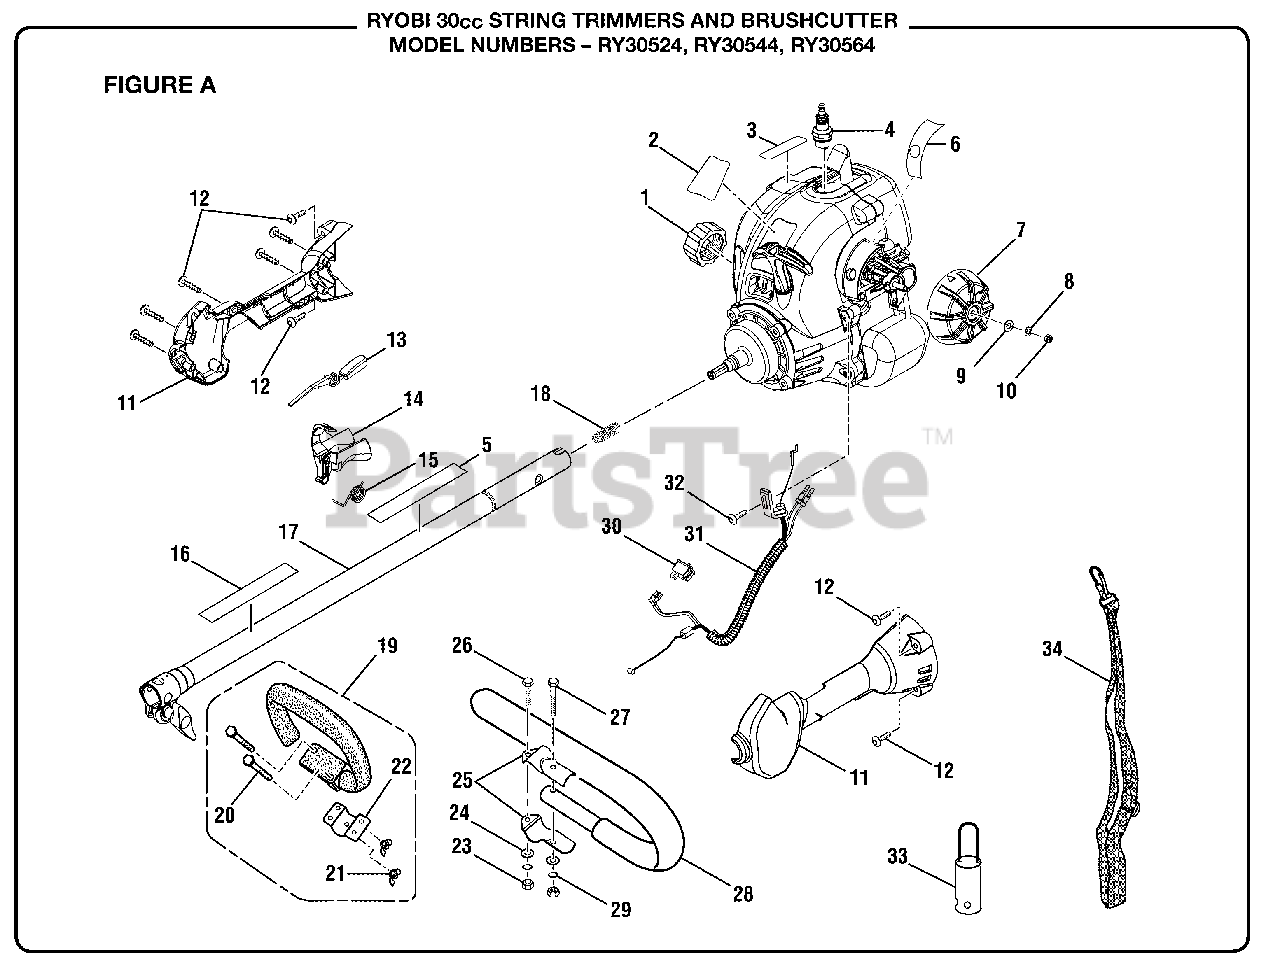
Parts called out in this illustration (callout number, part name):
1	Fuel Cap Assembly
2	Model Label (CS30)
3	Logo Label
4	Spark Plug
5	Starting Label
6	Choke Label
7	Choke Dial Cover
8	Wavy Washer
9	Flat Washer
10	Hex Nut (M4)
11	Control Handle Assembly
12	Screw (10-14 x 1 in.)
13	Trigger Lock
14	Trigger
15	Torsion Spring
16	Warning Decal (CS30 and SS30)
17	Upper Boom Assembly (CS30 and SS30)
18	Compression Spring
19	Front Handle Assembly (CS30 and SS30)
20	Bolt (M5 x 30 mm Hex Hd.) (CS30 and SS30)
21	Wing Nut (M5)
22	Handle Bar Clamp (CS30 and SS30)
23	Hex Nut (1/4-20) (BC30)
24	Washer (BC30)
25	Handle Bar Clamp (BC30)
26	Bolt (1/4-20 x 1 in Hex Hd.) (BC30)
27	Bolt (1/4-20 x 1-1/2 in Hex Hd.) (BC30)
28	"J" Handle and Grip (BC30)
29	Lock Washer (BC30)
30	Switch (Momentary Contact)
31	Throttle and Lead Assembly
32	Screw (10-24 x 7/8 in.)
33	Hanger Cap
34	Shoulder Strap (BC30)
